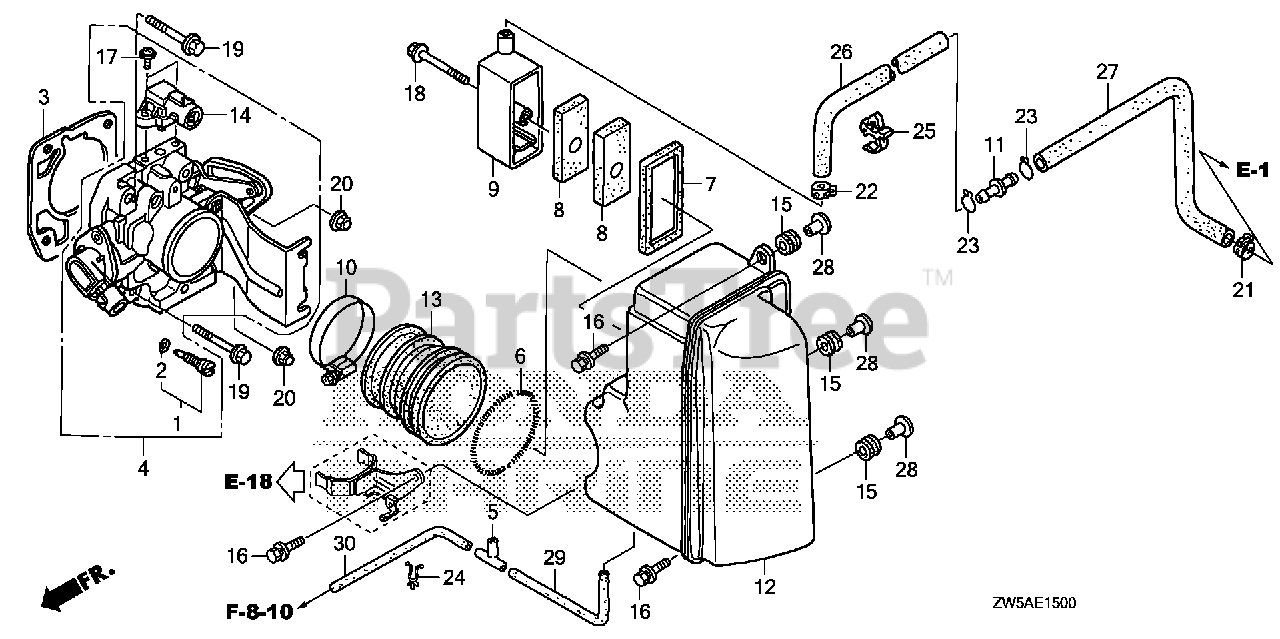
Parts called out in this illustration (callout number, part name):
2	O-RING (9.8X1.9)
3	GASKET, THROTTLE BODY (NIPPON LEAKLESS)
4	BODY ASSY., THROTTLE
5	JOINT A, VACUUM TUBE
6	SPRING, AIR FLOW TUBE
7	GASKET, BREATHER
8	ELEMENT, BREATHER
9	COVER, BREATHER ELEMENT
10	CLAMP, AIR FLOW (70)
11	JOINT, BREATHER TUBE
12	CASE, MUFFLER
13	GROMMET, MUFFLER
14	SENSOR ASSY., MAP
15	GROMMET, CASE (LOWER)
16	BOLT-WASHER (6X27) (CT200)
17	SCREW-WASHER (4X16)
18	BOLT, FLANGE (6X50)
19	BOLT, FLANGE (8X40)
20	NUT, CAP (8MM)
21	CLAMP, TUBE (D13)
22	CLAMP, TUBE (D15)
23	CLIP, TUBE (B12.5)
24	CLIP, DRAIN TUBE
25	CLIP, CABLE
26	TUBE A, BREATHER
27	TUBE B, BREATHER
28	COLLAR, MODULE IGNITION CONTROL CASE (CDI)
29	BULK HOSE, VINYL (3.5X6.5X8000) (3.5X6.5X110)
30	BULK HOSE, VINYL (3.5X6.5X8000) (3.5X6.5X200)
